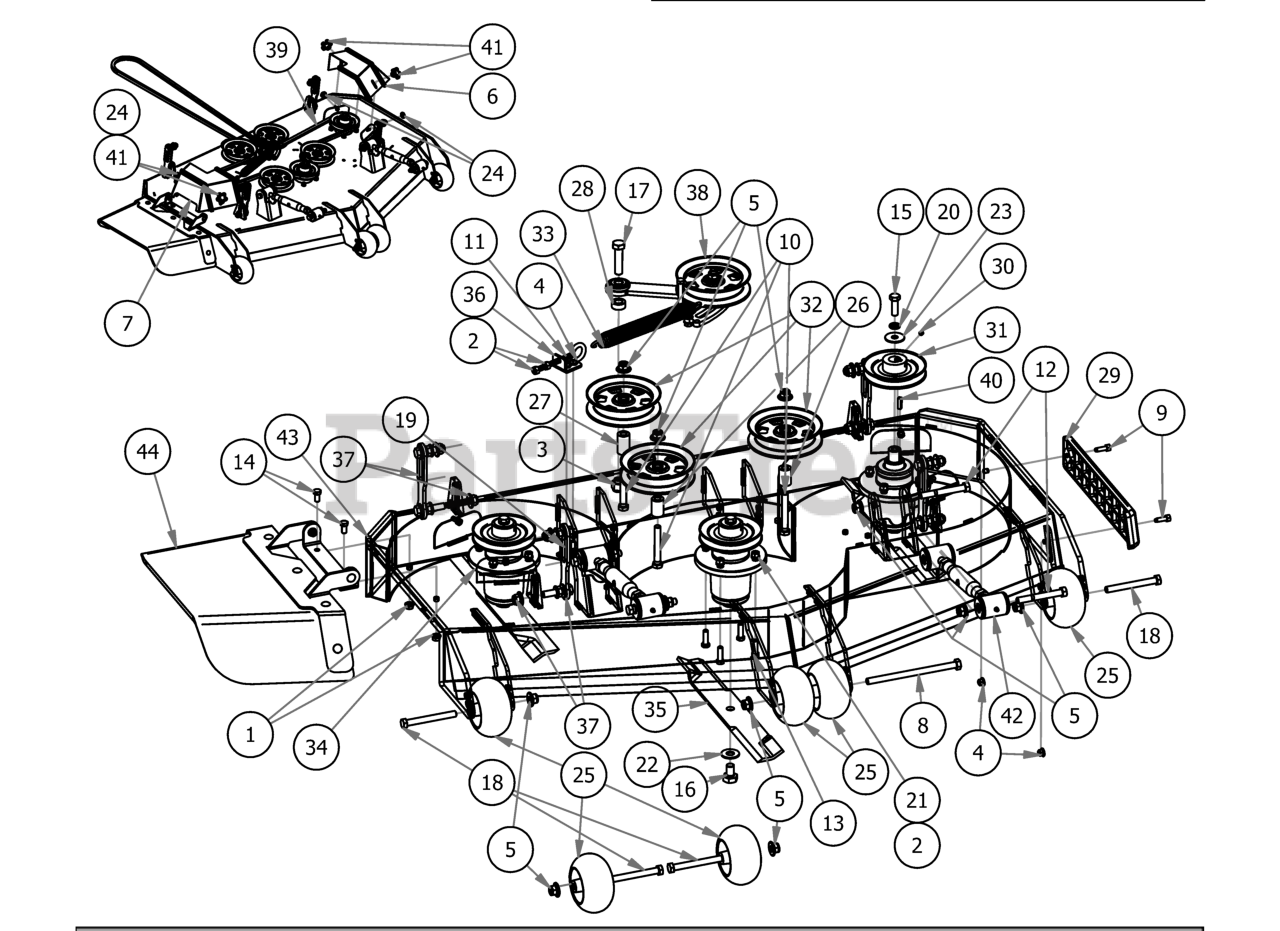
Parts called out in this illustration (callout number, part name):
1	3/8" Flange Nut
2	3/8" Hex Nut
3	5/8 Std NC Nylock Nut
4	5/16" Nylon Flange Nut
5	1/2-13 Nylon Flange Nut
6	2019 54" Left Outlaw Gen2 Pulley Cover
7	2019 54" Right Outlaw Gen2 Pulley Cover
8	1/2-13 x 8 Hex Bolt Grade 5
9	5/16-18 x 1 GR 5 Hex Bolt Zinc
10	1/2 x 3 1/2 Flange Bolt Grade 8
11	4" 3/8-16 Eye Bolt
12	1/2" x 4" Bolt (Grade 8)
13	3/8" x 1 1/4" Hex Bolt
14	3/8" x 3/4" Hex Bolt
15	1/2"-20 x 1 1/2 - Grade 5 Fine Thread Bolt
16	5/8" x 1 1/2" Grade 8 Hex Bolt (Fine)
17	5/8" x 2 1/2" Grade 5 Hex Bolt (Coarse)
18	1/2" x 4 1/2" Bolt
19	5/16" x 7/8" Carriage Bolt
20	1/2" Lock Washer
21	3/8" Lock Washer
22	5/8'' Flat Washer
23	1/2" Belleville Washer
24	.360 ID Plastic Washer-Black
25	2019 Deck Wheel
26	.502 ID X .750 OD X 1.500 Long Spacer
27	1 3/4" Pulley Spacer
28	5/8" x 1/" Collar W/One Set Screw
29	REVISED TRIM BUMPER_20180226
30	5/16 Set Screw
31	5.25" Deck Spindle Pulley
32	5-3/4 Idler Pulley
33	2019 Outlaw Gen2 Deck Spring
34	OUTLAW SPINDLE ASSEMBLY
35	54" Deck Fusion Blade For Outlaw
36	2019 Deck Eye Bolt Tab
37	Deck Hangar Assembly
38	2019 Rebel Rogue Deck Idler
39	B165 Belt-60 54" deck Outlaw
40	1/4" x 1" Key
41	5/16" Knob
42	Turnbuckle
43	2019 Sloped 54" Deck
44	2019 Outlaw Gen2 Chute Assembly
